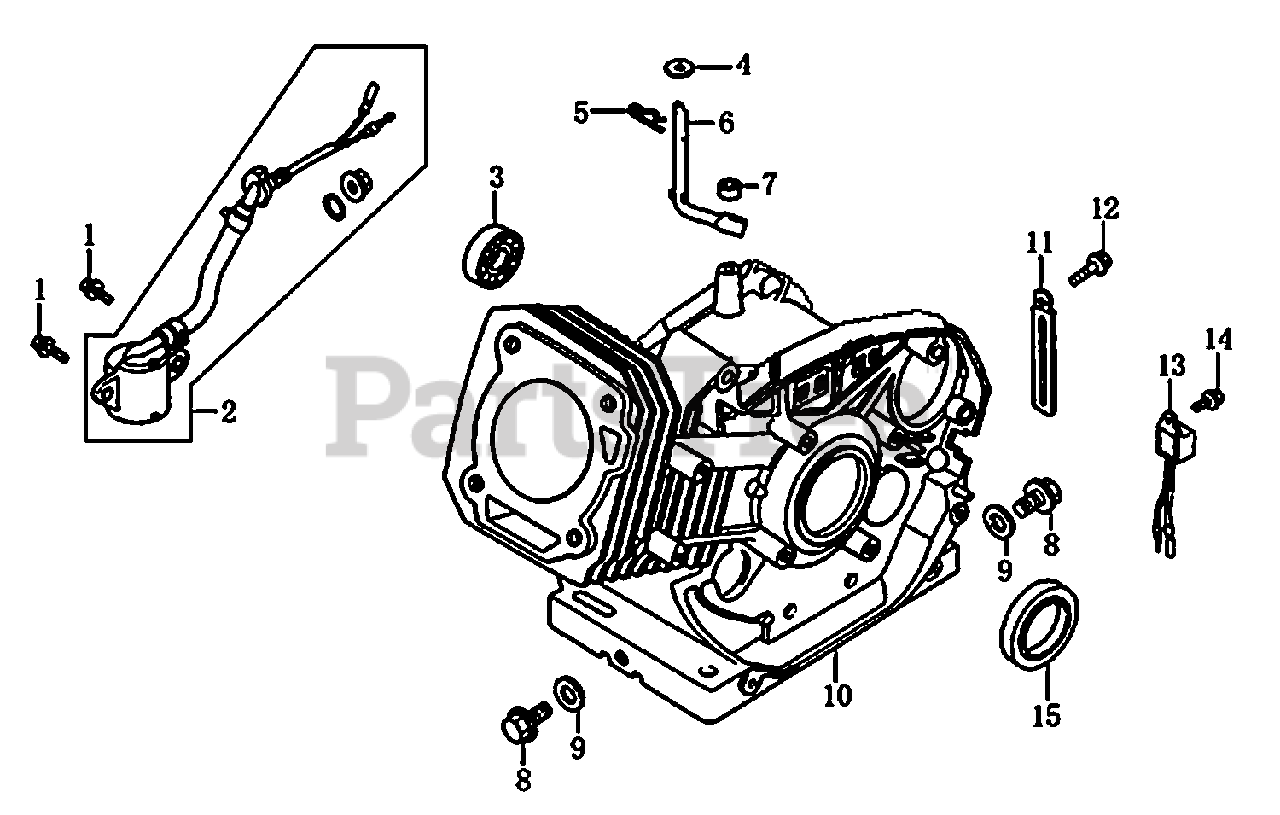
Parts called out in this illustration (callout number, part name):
1	BOLT, FLANGE, 6X14
2	SWITCH ASSY., OIL LEVEL
3	BEARING, RADIAL BALL, 6202
4	WASHER,8*16*1.2
5	PIN, LOCK, 10MM
6	SHAFT, GOVERNOR ARM
7	OIL SEAL, 8X14X4
8	BOLT, DRAIN PLUG
9	WASHER, DRAIN PLUG
10	CRANKCASE
12	BOLT, FLANGE, 6X12
13	ALERT UNIT,OIL
14	BOLT, FLANGE, 6X12
15	SEAL 35X52X7
